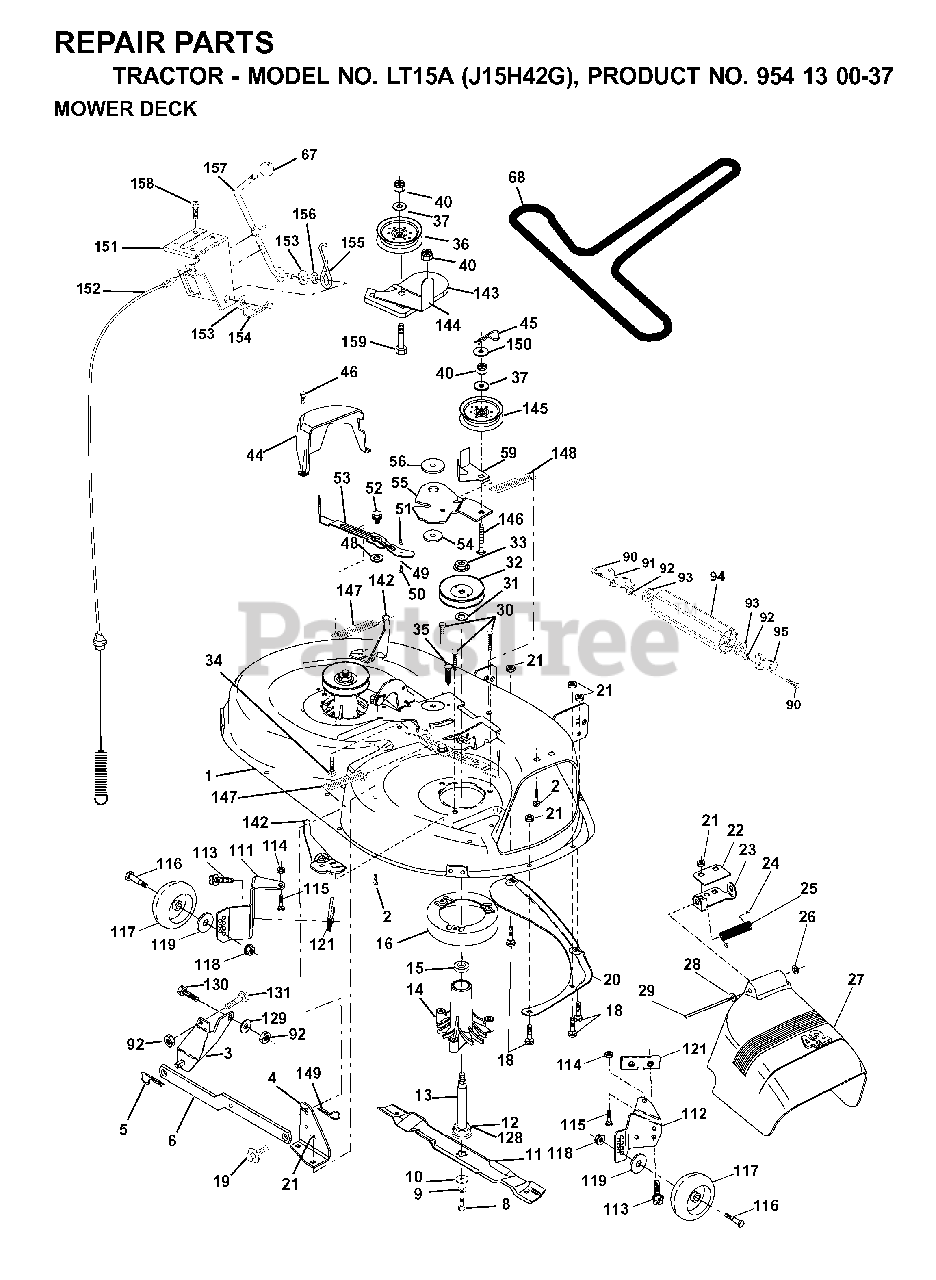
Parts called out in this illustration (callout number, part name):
1	42" DECK KIT
2	BOLT
3	BRKT ASM SWAY BAR
4	BRACKET SWAY BAR 42" DECK
5	RETAINER-SPRNG RB
6	REAR SUSP ARM
8	BLADE BOLT
9	LOCKWASHER
10	WASHER.BLADE
12	BEARING
13	SHAFT ASM VENT
14	HSG MANDREL
16	STRIPPER
17	BOLT
18	BOLT
19	BOLT SHD 5/16-18
20	BAFFLE.VORTEX
21	LOCKNUT
22	STIFFENER BRACKET
23	DEFLECTOR BRACKET
24	CAP-SLEEVE LT
25	SPRING TORSION
26	NUT PUSH M
27	SHIELD DEFLECTOR
28	WASHER
29	ROD.HINGE
30	SCREW THDROL ROLLING WASHER HD
31	WASHER
32	PULLEY/MANDREL
33	NUT
34	BOLT
35	FASTENER.XMAS.TREE
36	FLAT IDLER PULLEY
40	LOCKNUT
44	GUARD MANDREL LH BLACK
45	RETAINER M
46	SCREW.1/4-20X5/8
49	ROLLER ASSY
50	BOLT
53	ARM
54	HARDENED WASHER
55	ARM IDLER 42" MOWER LT/YT
56	SPACER.RETAINER.MOWER
59	GUARD, BELT
67	KNOB T (3/8 HOLE)
90	BOLT
91	BRACKET LH (A)
92	NUT
94	NOSE ROLLER
95	BRACKET RH (B)
111	BRACKET WHEEL GAUGE LH 42" DK
112	BRACKET WHEEL GAUGE RH 42" DK
113	SCREW 5/16"
114	NUT
115	BOLT
117	WHEEL.GAUGE.STANDARD
118	LOCKNUT
119	WASHER
121	BRACKET.EXTRD.GWL
128	WASHER FELT
129	WASHER
131	BOLT D
142	ARM SPRING BRAKE MOWER
143	BRACKET, ARM IDLER
144	KEEPER.BELT.42".CLUTCH.CABLE
145	PULLEY
146	BOLT, CARRIAGE IDLER
147	SPRING EXTENSION
148	IDLER RETURN SPRING
149	SPRING.RETAINER.YELLOW.ZINC
150	WASHER PM
151	BRACKET, CLUTCH CABLE
152	CLUTCH CABLE 42"
153	WASHER FLAT 3/8"
154	SPRING RETAINER
155	SPRING RETENTION LEVER
156	SPACER CLUTCH CABLE
157	ROD CLUTCH CABLE 3/8"
158	SCREW LT
159	BOLT
